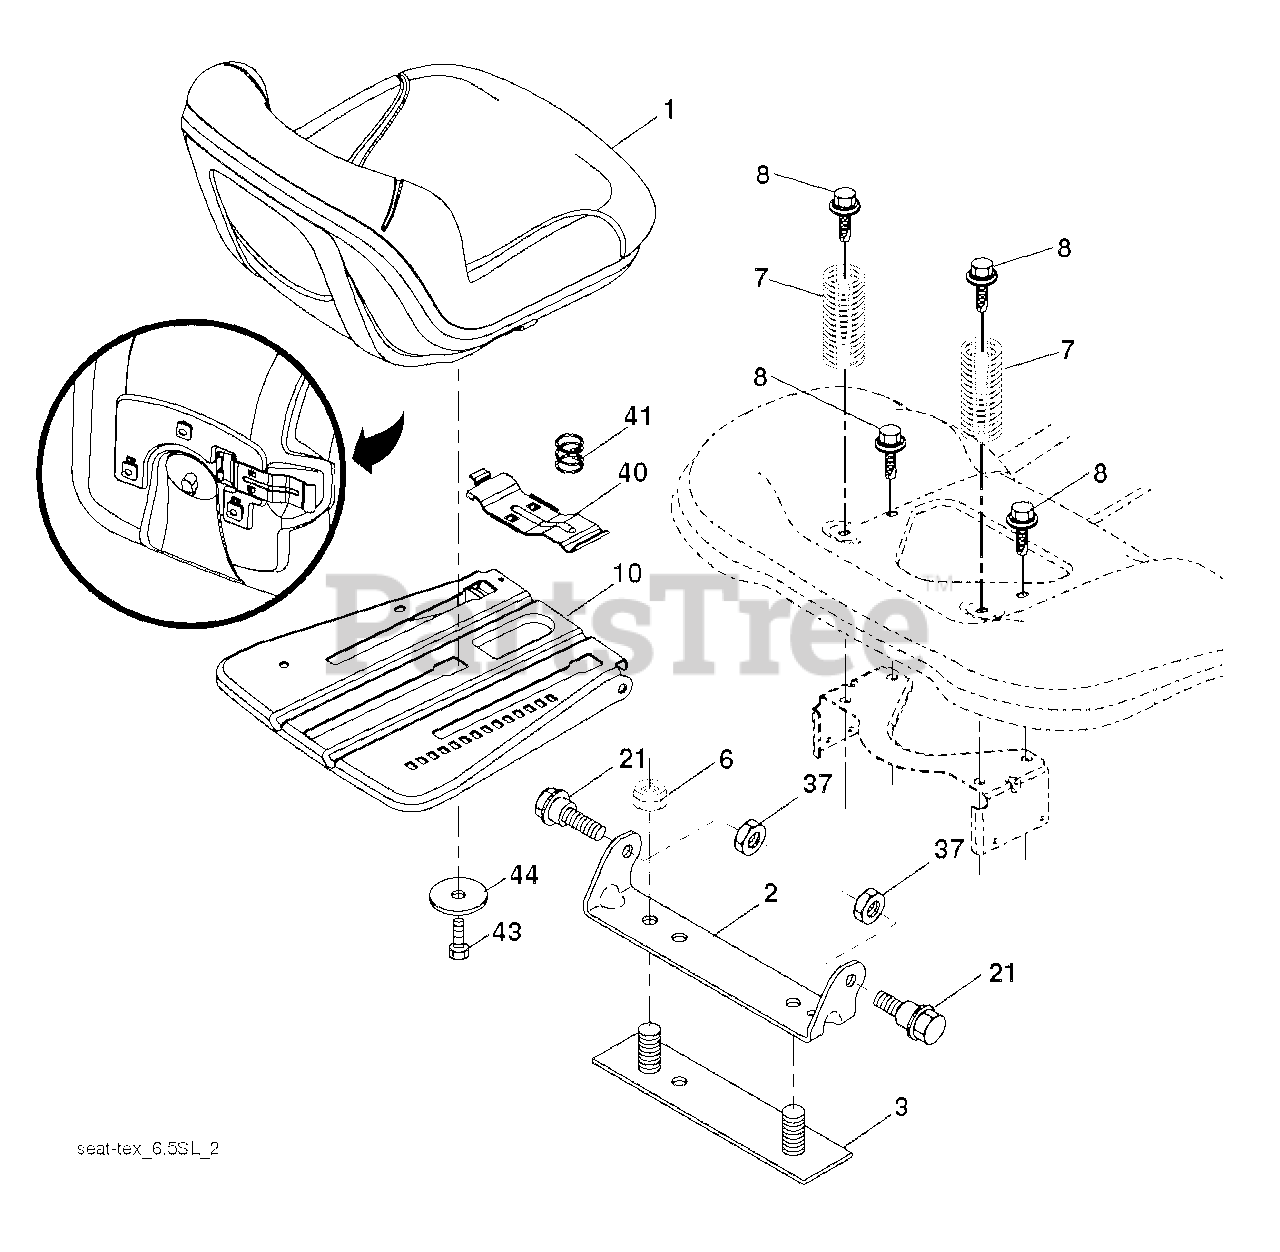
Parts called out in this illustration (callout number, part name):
1	SEAT.TH130.GREY.HUSQ.TEX
2	BRKT.PIVOT.FENDER
3	STRAP
6	NUT
7	SPRING COMPRESSION
8	BOLT, 5/16-18 X 1 3/4
10	PAN.ASM.SEAT.3PT
21	BOLT.SHOULDER.5/16-18
37	NUT.71038.31-18.HEX.NYLOCK
40	HANDLE.SLIDE.SEAT.TEX.BLACK
41	SPRING.LATCH.SEAT.TEX
44	WASHER 13/32 X 2-3/8 X 12GA
